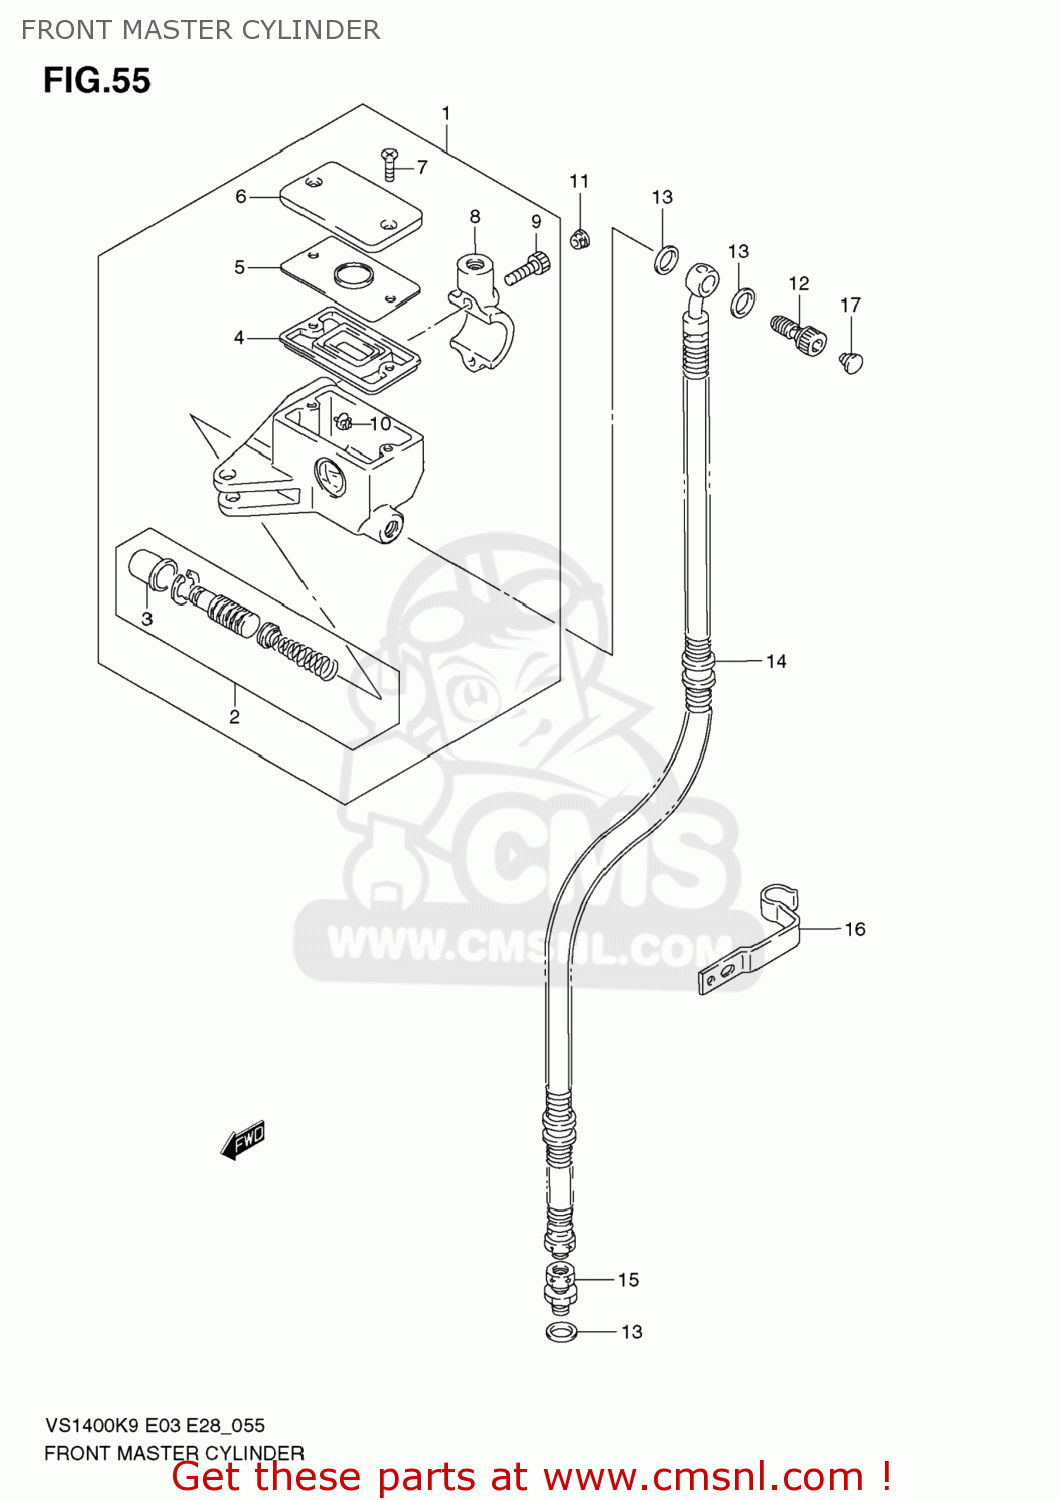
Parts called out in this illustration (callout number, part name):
1	CYLINDER ASSY,FR MASTER
2	PISTON/CUP SET
3	BOOT
4	5
5	PLATE,DIAPHRAGM
6	CAP
7	SCREW
8	HOLDER
9	BOLT
10	PROTECTOR
11	CAP(OD:10)
12	BOLT UNION
13	WASHER(10X15X1.5)
14	HOSE,FR BRAKE
15	ADAPTER,BRAKE HOSE
16	GUIDE,BRAKE HOSE
17	CAP(OD:12)
